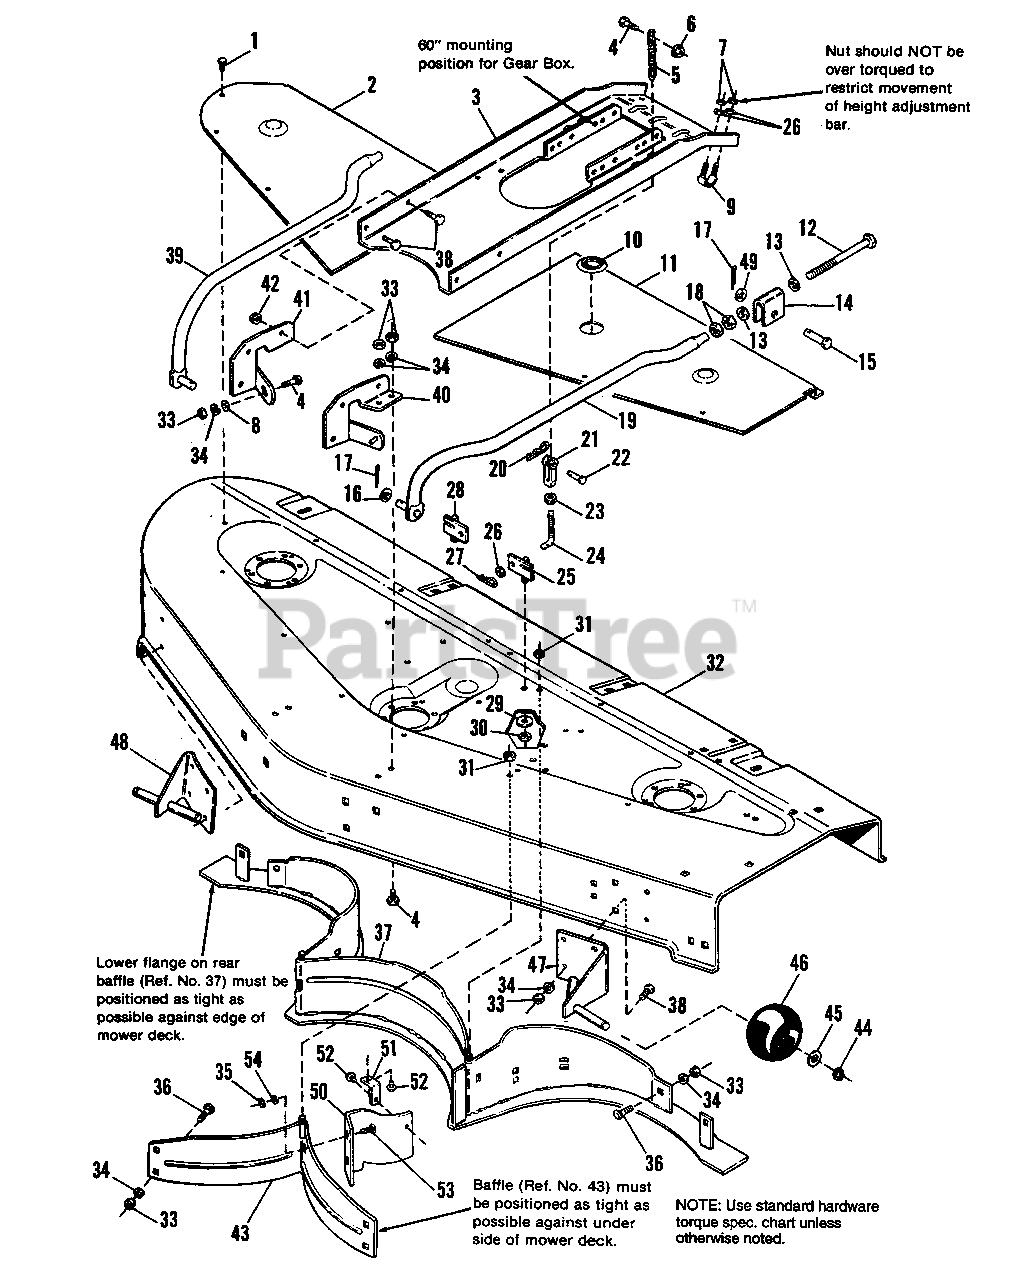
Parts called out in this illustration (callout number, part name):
1	SCREW, Hex, Taptite, 1/4-20 x 3/8
2	COVER, Mower, R.H.
3	SUPPORT, "U" Channel
4	CAPSCREW, Hex Hd., 3/8-16 x 1
5	CHAIN, 5 Link
5	CHAIN, 6 Link
6	NUT, Hex, Flange lock 3/8-16
7	NUT, Centerlock, 5/16-18
8	WASHER, 11/32
10	PLUG, Mower Cover, L.H.
11	COVER, Mower, L.H.
12	CAPSCREW, Hex, 5/8-18 x 5-1/2
13	WASHER, 5/8
14	TRUNNION
15	PIN, Trunnion
16	WASHER, 21/32
17	PIN, Cotter, 1/8-1
18	NUT, Hex, Jam, 5/8-18
19	ARM ASSY., L.H.
20	CLIP, Hair Pin
21	CLEVIS, Lift
22	PIN, Rivet, Clevis
23	NUT, Hex, Jam, 5/16-18
25	BRACKET ASSY., Lift, L.H.
26	WASHER, Plain, 5/16 x 3/4 x 1/16
27	CLIP, Hair Pin
28	BRACKET ASSY., Lift, R.H.
29	WASHER, Plain, 13/32 x 1-1/2 x 1/8
30	NUT, Hex, Centerlock, 3/8-16
31	NUT, Hex, Centerlock, 5/16-18
32	HOUSING, 60" Mower (Incl. Safety Decals)
33	NUT, Hex, 3/8-16
34	LOCKWASHER 3/8
35	Nut, Hex, 5/16-18
36	CARRIAGE BOLT, 3/8-16 x 1
37	BAFFLE, Mower
38	CAPSCREW, Hex, 3/8-16 x 7/8
39	ARM ASSY., R.H.
40	BRACKET ASSY., L.H.
41	BRACKET ASSY., R.H.
42	NUT, Hex, Whizlock 3/8-16
43	BAFFLE ASSY., Front
44	RING, Retaining, Ext., 1/2
45	WASHER, Plain, 1/2 x 1
46	GAUGE WHEEL
47	BRACKET ASSY., Gauge Wheel, L.H.
48	BRACKET ASSY., Gauge Wheel, R.H.
49	WASHER, Plain
50	BAFFLE, Discharge
51	BRACKET, Mower
52	SCREW, Taptite, 5/16-18 x 1/2
53	BOLT, Carriage, 5/16-18 x 3/4
54	LOCKWASHER
